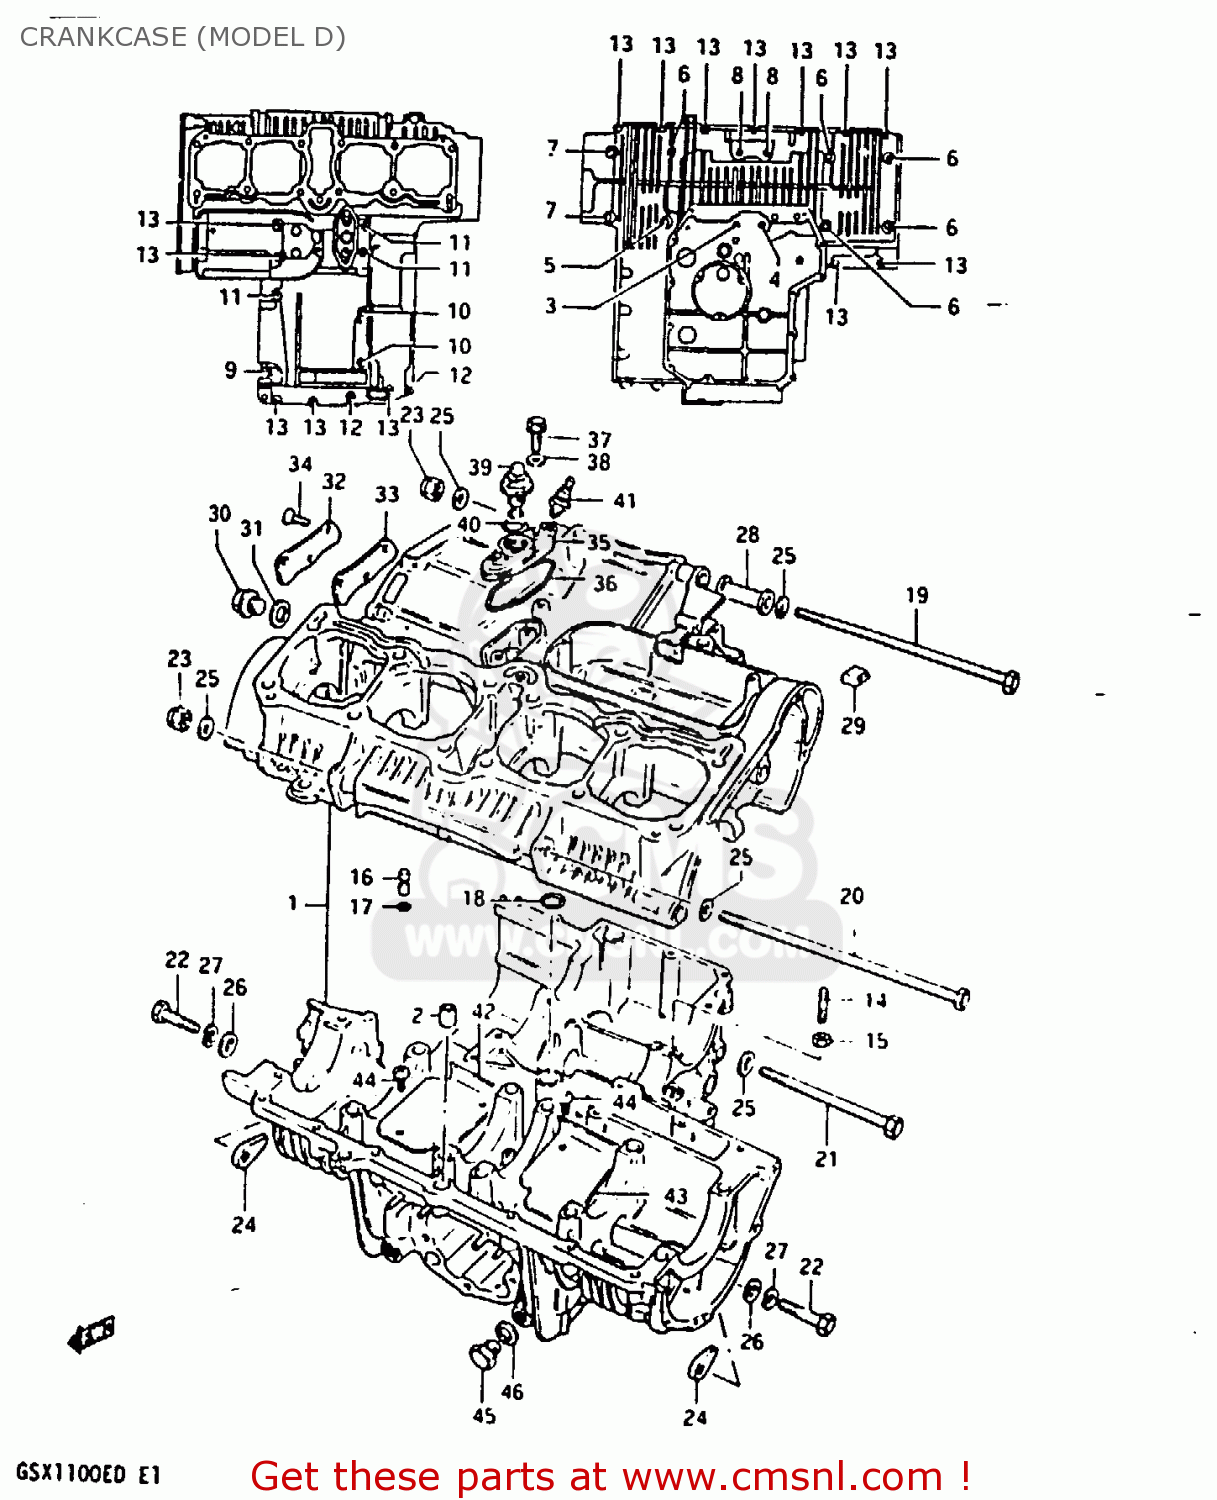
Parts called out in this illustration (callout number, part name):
1	CRANKCASE SET
2	PIN
3	BOLT 8X155
4	BOLT
5	BOLT
6	BOLT (8X90)
7	BOLT (8X65)
8	BOLT 8X60
9	BOLT (8X50)
10	BOLT
11	BOLT (6X75)
12	BOLT 6X55
13	BOLT (6X40)
14	STUD BOLT
15	NUT
16	UNION
17	O RING(D:1.05,ID:3.1)
18	O RING(D:3.2,ID:12.9)
19	BOLT 10X230
20	BOLT
21	BOLT
22	BOLT (10X60)
23	NUT
24	NUT
25	WASHER
26	WASHER(10.5X20X3.2)
27	LOCK WASHER
28	SPACER,ENGINE MOUNT(L:65)
29	PAD,CYLINDER
30	PLUG (14X12)
31	GASKET(14X19.2X2) (NAS)
32	CAP,OIL GALLERY
33	GASKET,OIL GALLERY (MCA)
34	SCREW
35	HOUSING,OIL PRESSURE SWITCH
36	O RING,PRESSURE SWITCH HOUSING
37	BOLT
38	GASKET (NAS)
39	SWITCH ASSEMBLY
40	O RING(D:1.9,ID:18.8)
41	GAUGE ASSEMBLY,OIL TEMPERATURE
42	PLATE,OIL SEPARATOR
43	PLATE,OIL SEPARATOR
44	SCREW
45	PLUG
46	GASKET(14X19.2X2) (NAS)
